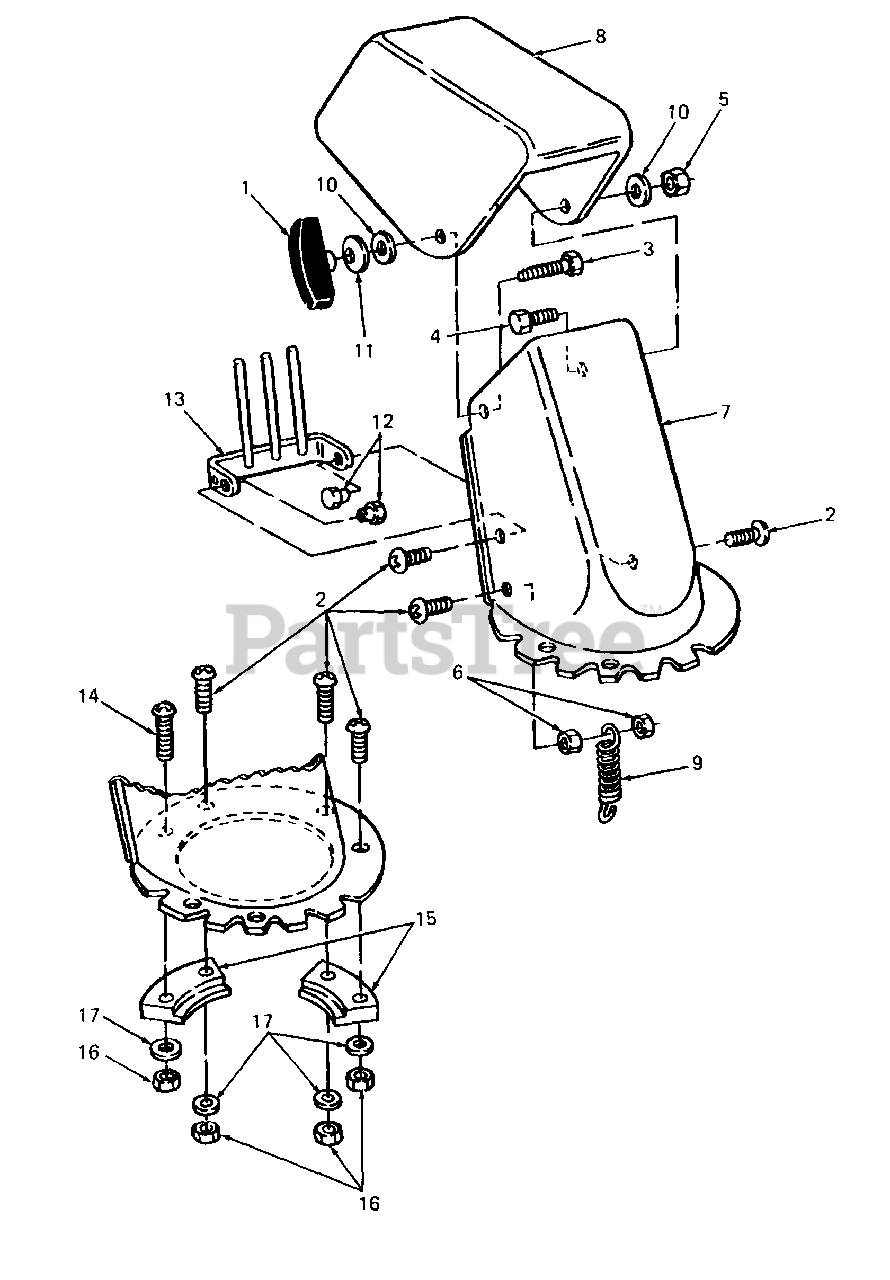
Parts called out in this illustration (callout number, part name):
1	Knob, Handle
2	Screw, Truss Mach, 1/4-20 X .75 Lg
3	Bolt, Carriage, 5/16-18 X 1.0 Lg
4	Screw, Truss Mach, 5/16-18 X .75 Lg
5	Nut, Hex Center Lock, 5/16-18
6	Nut, Hex Center Lock, 1/4-20
7	Chute, Lower, 6" Dia
8	Chute, Upper, 6" Dia
9	Spring, Extension, .36 OD X 2.5 Lg
10	Washer, Flat, .344 X 1.125 X .125 Thk
11	Washer, Bell, .345 X .88 X .060 Thk
12	Nut, Shoulder, 1/4-20
14	Screw, Truss Mach, 1/4-20 X 1.0 Lg
15	Keeper, Chute Flange
16	Nut, Hex Patch Lock, 1/4-20
17	Washer, Flat, .281 X .50 X .063 Thk
